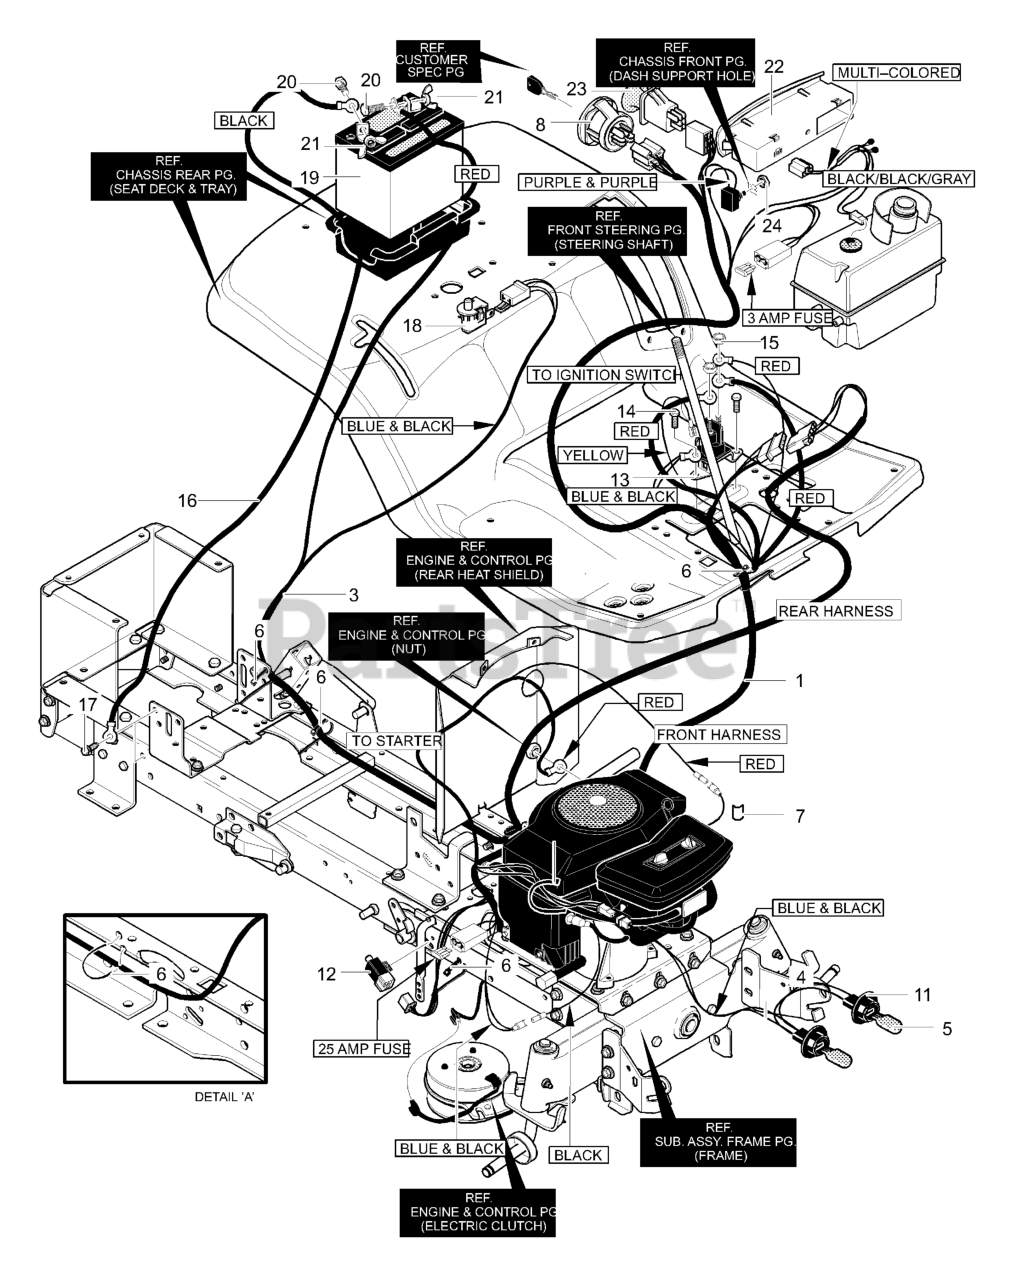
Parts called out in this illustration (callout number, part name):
1	HARNESS, WIRE
3	HARNESS, REAR WIRE
4	WIRE ASSEMBLY, HEADLIGHTS
5	BULB, LIGHT
6	TIE, CABLE BLACK
7	WIRE CLIP, ADHESIVE
8	SWITCH, IGNITION
11	SOCKET, LAMP
12	SWITCH, LIMIT
13	SOLENOID
16	WIRE, GROUND
18	SWITCH, SEAT
19	BATTERY
20	BOLT
21	WINGNUT
22	ELECTRONIC DIAGNOSTIC
23	SWITCH, PTO
24	NUT, PLASTIC
